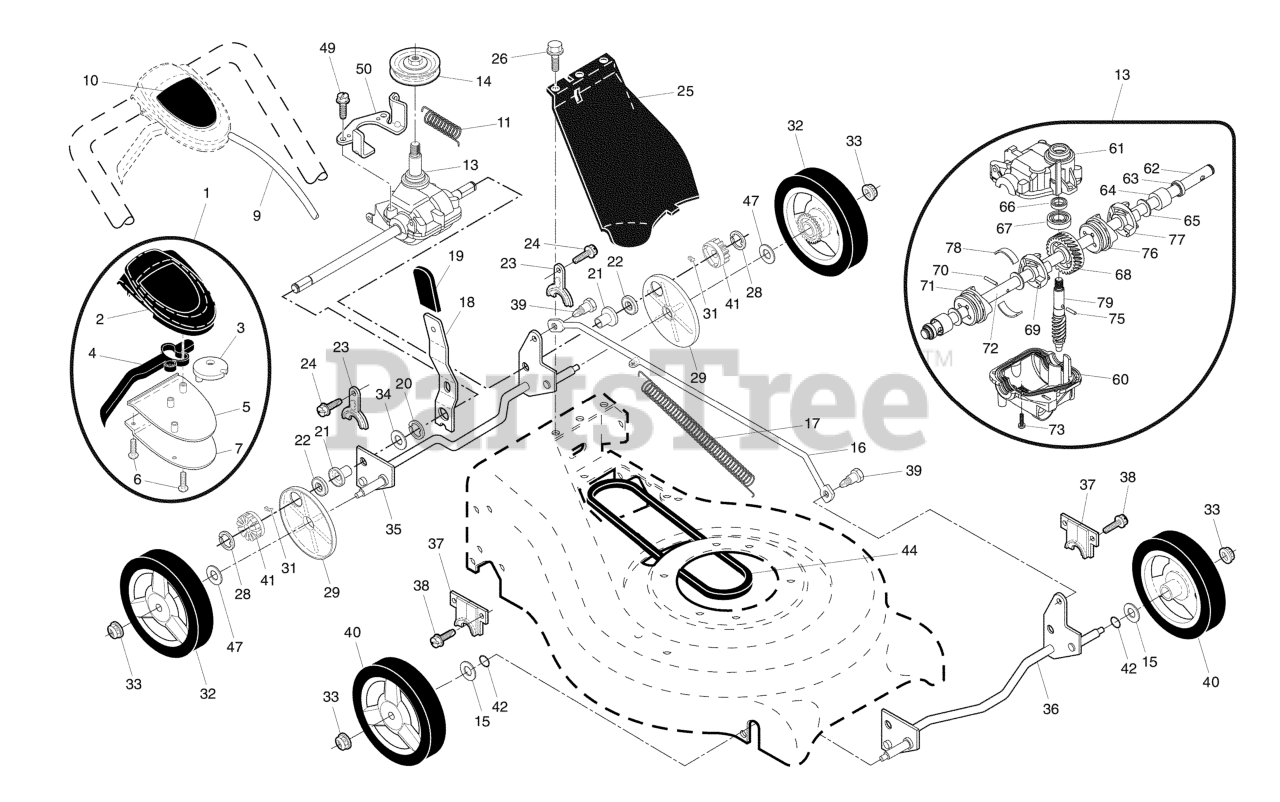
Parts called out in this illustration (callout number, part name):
1	DRIVE CONTROL ASSY, AUTO WALK
2	COVER TOP AUTO WALK CONTROL
3	PULLEY.CAM.DRIVE.CONTROL.EZ
4	LEVER, AUTOWALK DRIVE CONTROL
5	COVER BOTTOM AUTO WLK CONTROL
6	SCREW, PHILLIPS HEAD 10 X 5/8
7	BRACKET.DRIVE.CONTROL.MOUNT.BL
9	CABLE.ASSY.RGD.EZ.AUTO
10	DECAL, DRIVE
13	TRANSMISSION.21.RWGD.AUTO.SP
14	PULLEY.1.PIECE
15	WASHER.FLAT.1/2
16	ROD.CONNECTING.SPT.BLACK
17	SPRING EXTENSION
18	SPRING.SELECTOR.SPT.21
19	KNOB, SELECTOR SPRING
21	BEARING SUPPORT
22	BEARING
23	BRACKET
25	COVER.DRIVE.21.RWGD.MO
28	E-RING 7/16 RE
29	COVER.DUST.WHEEL
31	PAWL, DRIVE
32	WHEEL & TIRE ASSY, REAR
33	NUT.HEX.FLANGE.3/8-16.LO(3 2)
35	SHAFT ASSY REAR
36	SHAFT ASSY, FRONT
37	RETAINER.FRONT.SHAFT
39	SHOULDER BOLT SEMI GIMLET PT.
40	WHEEL & TIRES ASSY, FRONT
41	PINIION.14.TOOTH.RGD
42	O-RING..070X.487.NEOPRENE
44	BELT.RGD.VS
47	WASHER FLUT
50	BELT KEEPER
60	CASE, LOWER
61	CASE UPPER
62	SHAFT OUTPUT LONG
63	SEAL.OUTPUT.SHAFT
66	SEAL INPUT SHAFT
68	GEAR 28 TEETH
69	DOG.FIXED.LH.32003
70	PIN 3.50.337 - 33733
71	DOG.MOVEABLE.LH.32005
72	SHAFT OUTPUT SHORT (12294)
75	PIN 7 33732
76	DOG.FIXED.RH.32004
77	DOG.MOVEABLE.RH.32006
78	SPRING LEAF
79	SHAFT WORM
